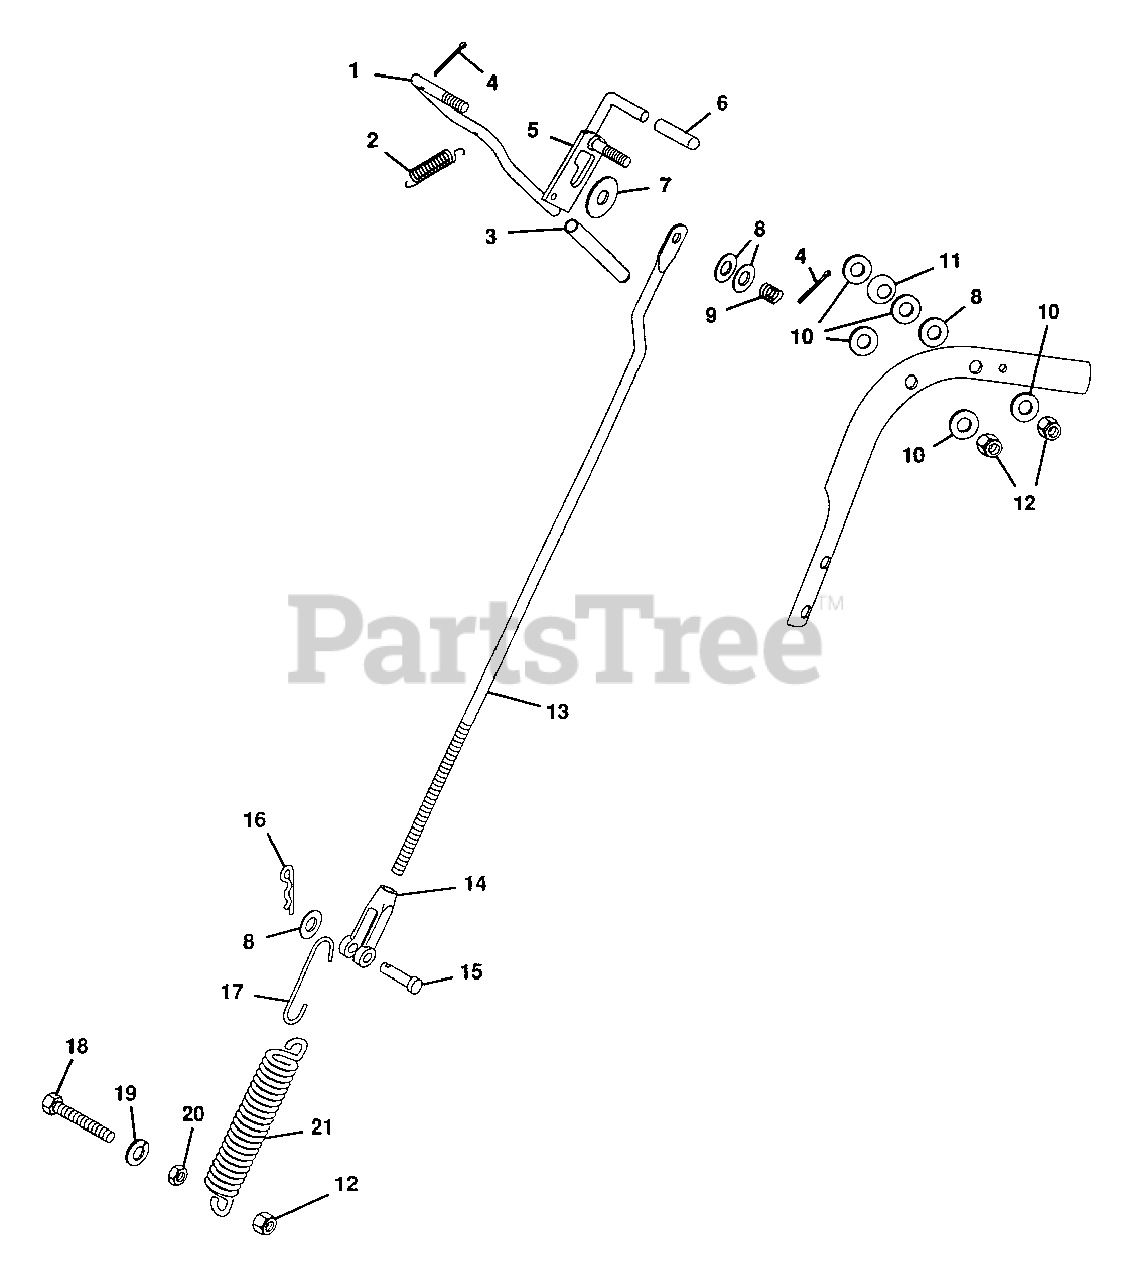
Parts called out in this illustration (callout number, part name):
1	Lever, Hard Clutch
2	Spring, Extension
3	Grip, Hand Clutch Lever
4	Pin, Cotter .09x.75
5	Weldment, Neutral Lock Lever
6	Tip, Brake Lock Lever
7	Washer, Flat .438x1.375x.083
8	Washer, Flat .406x.812x.065
9	Spring, Compression
10	Washer, Nylon .375x75x.06
11	Washer, Spring .375 I.D.
12	Nut, Lock 3/8-16
13	Rod, Steering Control
14	Clevis, 3/8-24 Adjustable
15	Pin, Clevis
16	Pin, Cotter Hair
17	Hook, Spring
18	Bolt, Hex 3/8-16x2.5
19	Washer, Lock 3/8 Reg.
20	Nut, Hex 3/8-16
21	Spring, Ext. LE-105J-7
